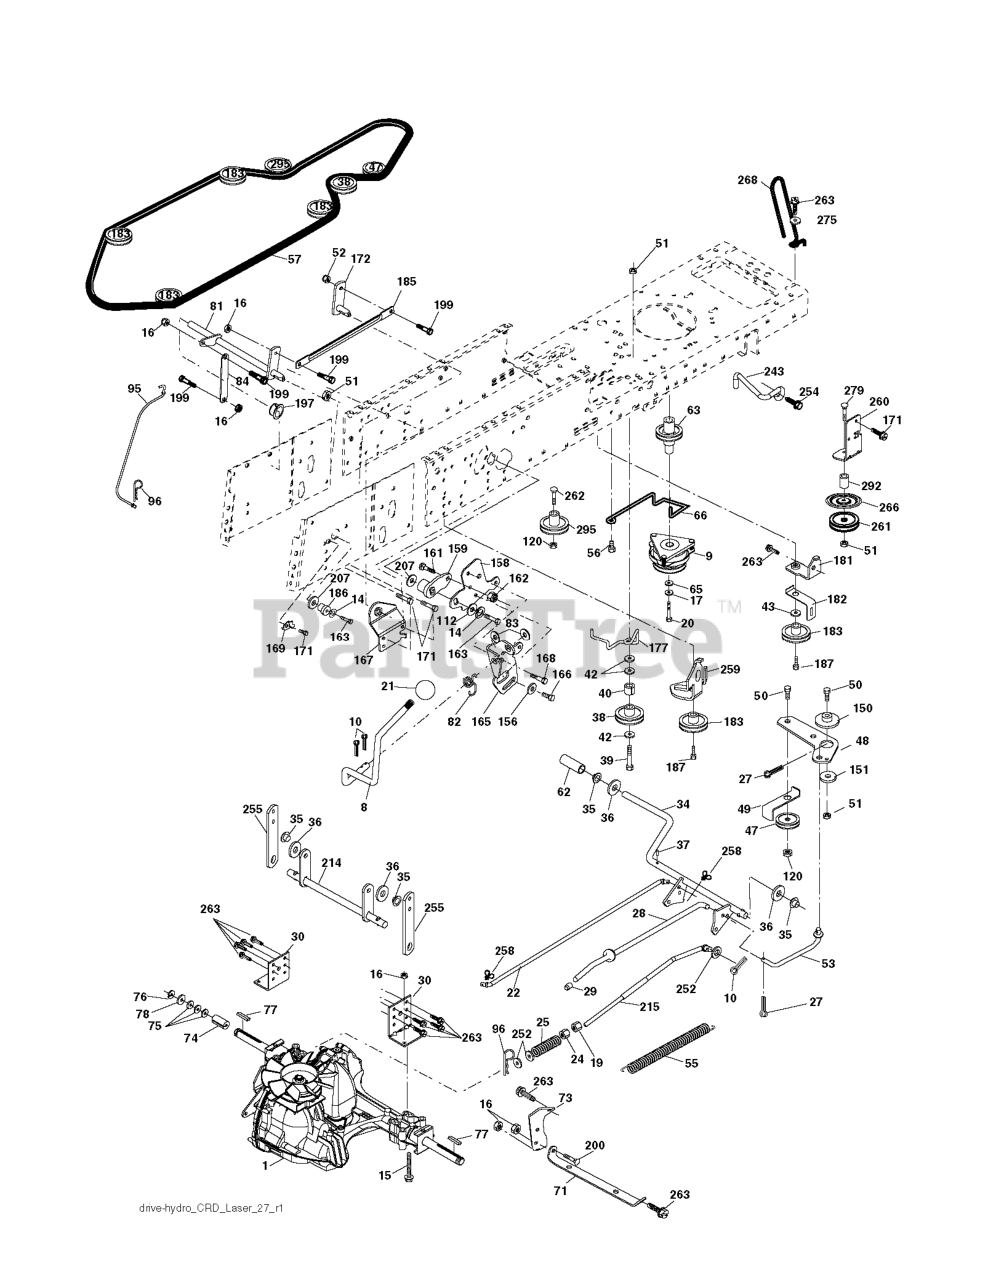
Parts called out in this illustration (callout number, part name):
8	ROD SHIFT FENDER ADJUST LT
10	PIN COTTER
14	LOCKWASHER
15	BOLT HEX 5/16-18 GR 5
16	NUT.71038.31-18.HEX.NYLOCK
19	NUT
20	BOLT HEX 7/16-20X4-1/4"
21	KNOB.DUCKHEAD.1/2
22	ROD
24	NUT
25	SPRING BRAKE ROD
27	COTTER PIN
28	ROD, PARKING BRAKE
29	CAP
30	BRKT, TRNSXLE MNT 20"
34	SHAFT, FOOT PEDAL
35	BEARING.NYLON
36	WASHER LT
37	DRIVE PIN
38	PULLEY.FLAT
42	WASHER
43	WASHER T
47	IDLER PULLEY
48	BELLCRANK, CLUTCH
49	RETAIN BELT
50	BOLT.3/8-16X1.50
52	LOCKNUT
53	LINK.CLUTCH.7.66.2005
55	SPRING, RETURN LT
56	SCREW.3/8-16
57	V-BELT 113"
62	PEDAL COVER T
63	PULLEY.ENGINE.CVX.LT
65	LOCKWASHER
66	KEEPER BELT ENGINE
71	STRAP TORQUE LH HYDRO
73	STRAP TORQUE RH HYDRO
74	SPACER AXLE
77	SQUARE KEY
81	ASM.CROSS.SHAFT.REAR.CRD.0510
82	SHIFT SPRING
83	WASHER
84	LINK.PNT.TRANSAXLE.0510.CRD
95	LINK
96	RETAINER M
112	WASHER LT
120	NUT LOCK FLG 3/8-16 UNC
150	BUSHING.BELLCRANK.GRD.DR
151	WASHER 12/32X2X10GA
156	WASHER.SRRTD.5/16
158	BRACKET
159	RB HUB.SHIFT
161	BOLT
162	NUT.CROWNLOCK.1/4
163	BOLT
165	RP BRACKET
166	CAPSCREW.HXHD.FLG.5/16-18X.625
167	BRACKET.SUPT.SHIFT.CRD
168	BOLT.SHOULDER.5/16-18X
169	PLATE.FASTENING.CROSS.SHAFT
171	SCREW LT
172	LINK
181	BRACKET
182	BELT GUIDE
183	PULLEY.V-IDLER.GRND.DR
185	LINK
186	HUB.TAPERED.ROUND.CRD
187	BOLT.5/16-18X1.25
197	NYLINER SNAP 5/8" ID
199	BOLT SHOULDER 5/16-18 UNC
200	BOLT
207	WASHER NYL
214	LEVER
215	ROD
243	BRACKET, ANTI-ROTATION
252	WASHER
254	SCREW 3/8-16X1
255	SHAFT
258	CLIP RETAINER
259	BRACKET
261	FLAT IDLER PULLEY
263	SCREW, 3/8-16X3/4
266	PROTECTOR
268	GUARD MUFFLER
275	WASHER
279	BOLT
292	SPACER
295	PULLEY IDLER COMPOSITE
